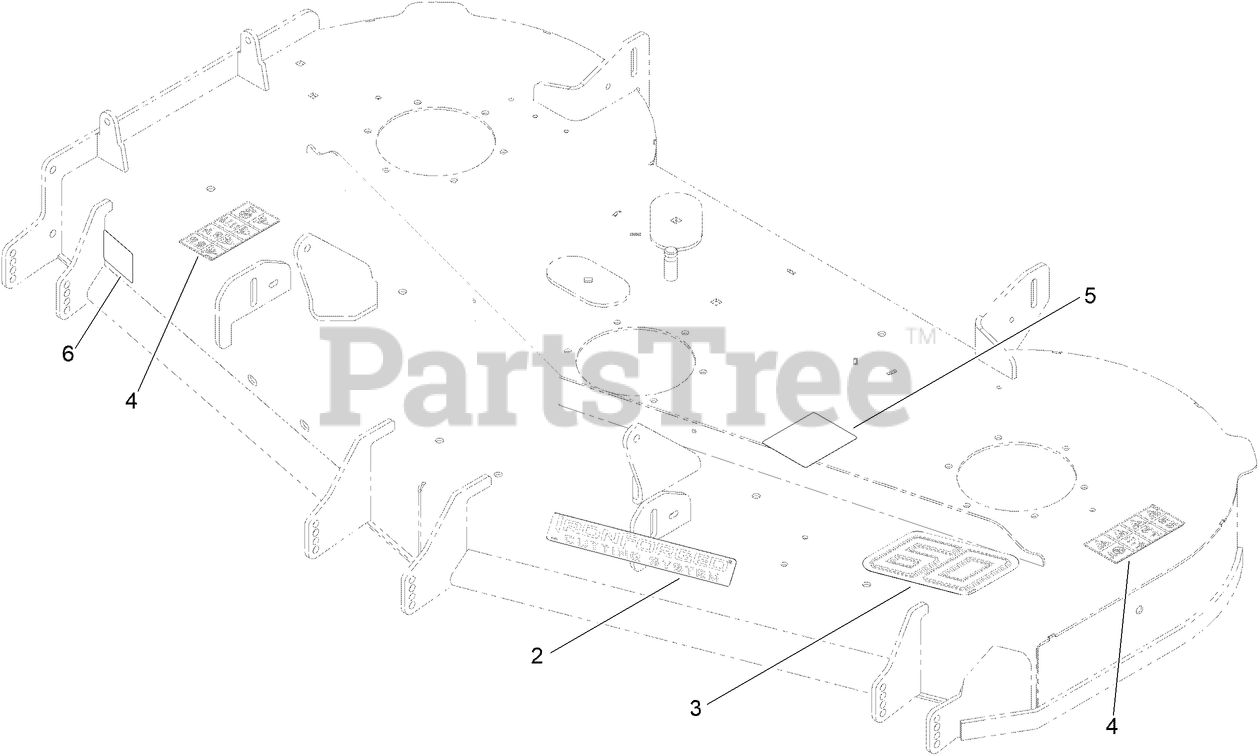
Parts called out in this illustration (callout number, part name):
2	DECAL - IRON FORGED
3	DECAL - DECK 60
4	DECAL-DANGER, DECK
5	DECAL-ROUTING, BELT
6	DECAL-SCALP, ANTI
